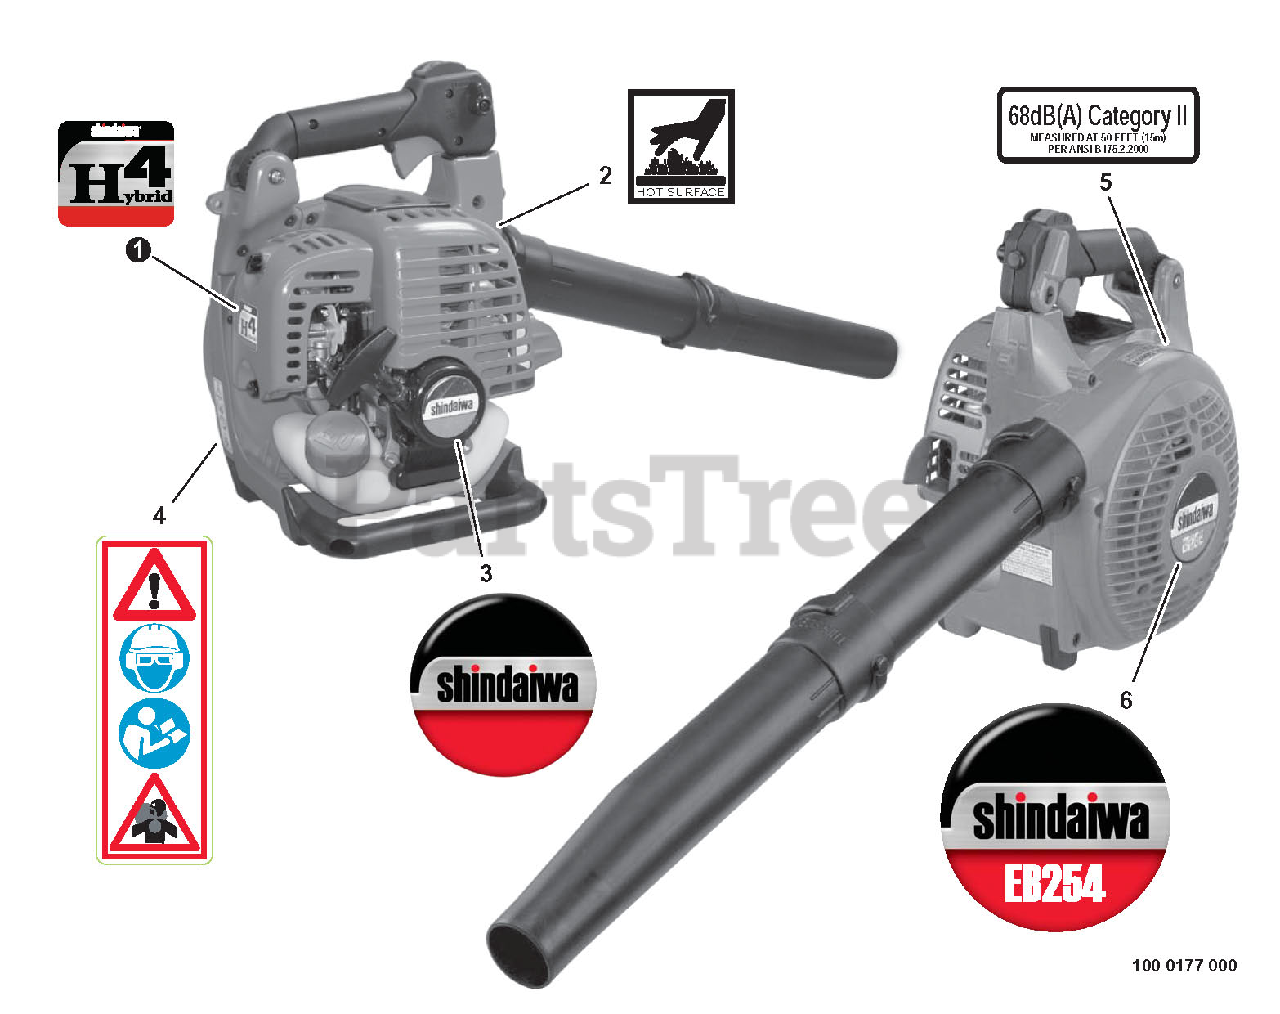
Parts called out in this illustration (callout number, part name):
1	LABEL - H4
2	LABEL - HOT SURFACE
3	LABEL - SHINDAIWA
4	LABEL - CAUTION
5	LABEL - NOISE 68dB(A) CAT II
6	LABEL - MODEL EB254
